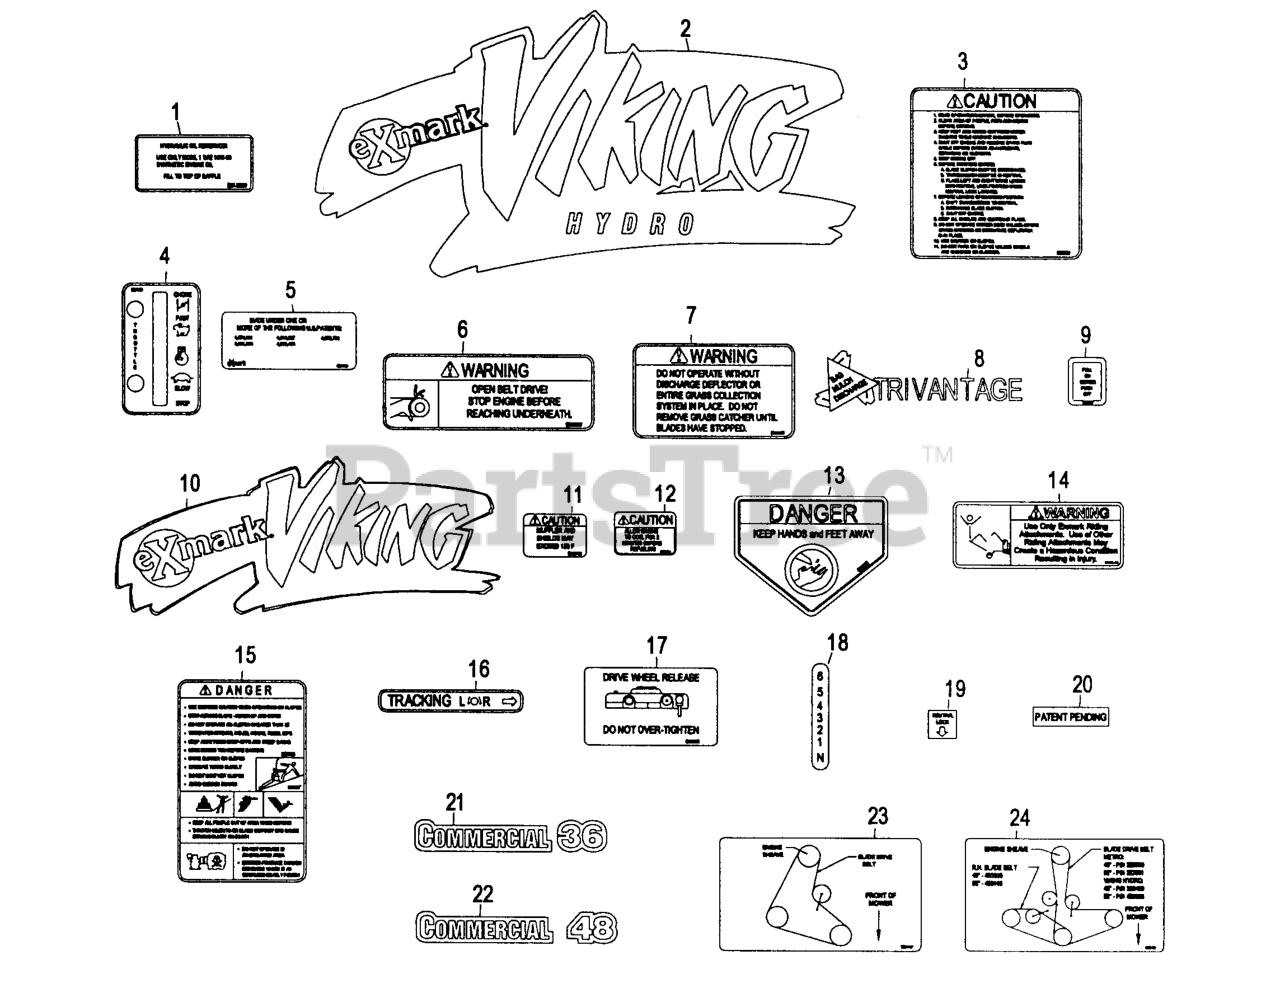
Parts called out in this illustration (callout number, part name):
1	DECAL,HYD TANK
3	DECAL,INSTRUCTIONAL
6	DECAL,BELT DRIVE
7	DECAL-WARNING, DISCHARGE
13	DECAL-DANGER
14	DECAL,SULKY WARNING
16	DECAL,TRACKING ADJUST
17	DECAL,DRIVE RELEASE
18	DECAL - SHIFTER
19	DECAL,NEUTRAL LOCK
20	Decal, Patent Pending
21	DECAL,COMMERCIAL 36
22	DECAL,COMMERCIAL 48
23	DECAL,BELT ROUTING 32/36
